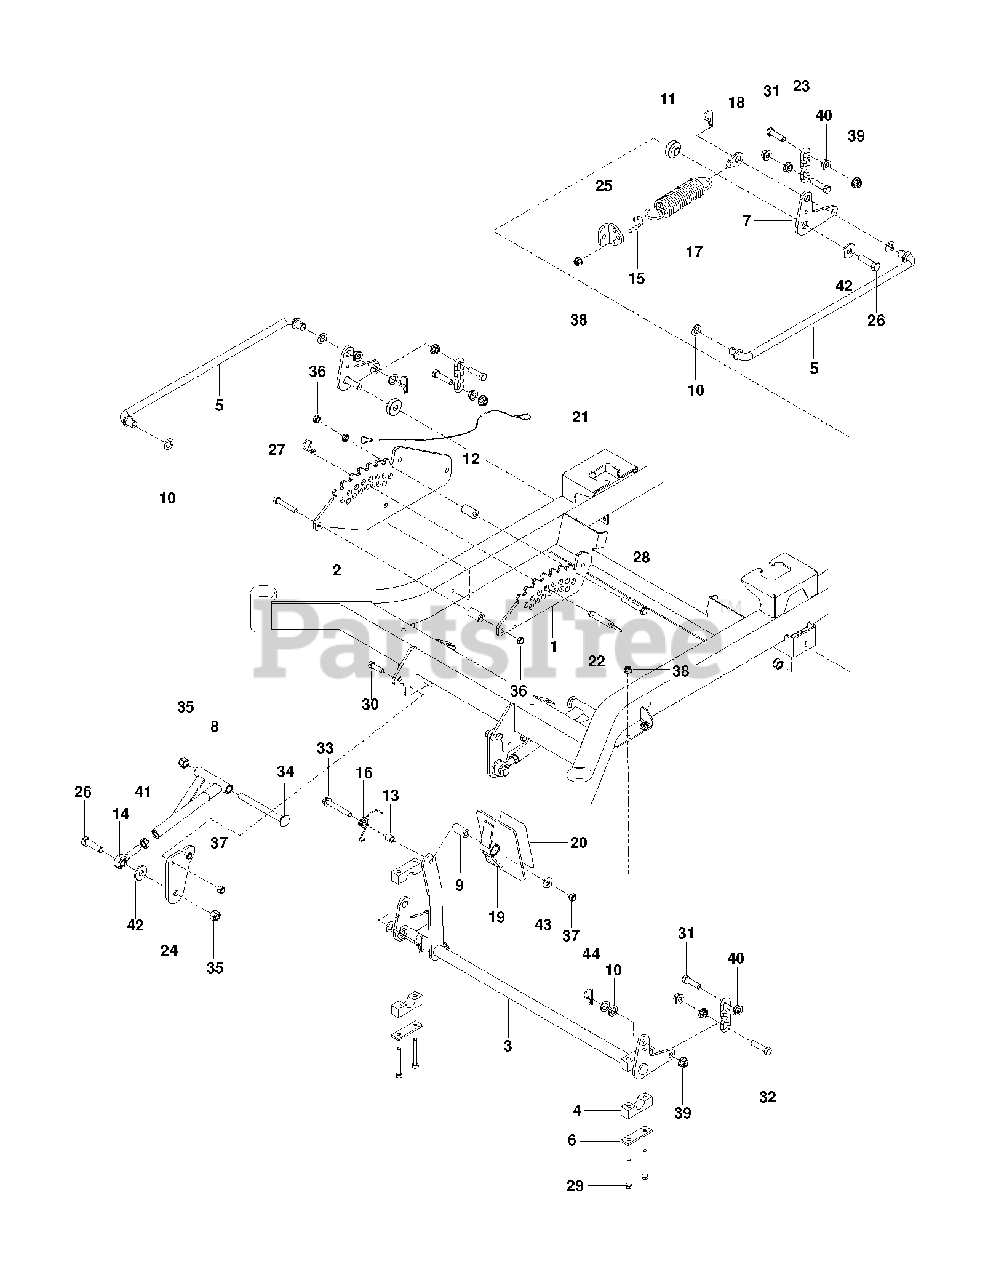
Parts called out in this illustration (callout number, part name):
1	PLATE, INSIDE 5", HEIGHT
2	PLATE, 5" HEIGHT
4	PILLOW BLOCK
5	CROSS LINK
6	REINFORCEMENT BAR
7	BELLCRANK, REAR LIFT
8	STRUT, DECK, BLK
9	BUSHING, SLEEVE
10	BUSHING
11	IDLER SPACER
12	DECK LIFT SPACER
14	ROD END
16	SPRING, TORSION
18	TAB, SPRING
19	PEDAL, FOOT, WELDMENT
20	FOOT PAD
21	LANYARD
22	HITCH PIN
23	LIFT CHAIN - 3 LINK
24	MOUNT, STRUT
25	MOUNT, SPRING
26	HCS 1/2-13 X 1 3/4 GR 8
27	HCS 3/8C X 2 1/4
28	HCS 3/8C X 2 1/2
29	HCS 5/16C X 2-3/4
30	HCS 3/8C X 1 1/4 GR5
31	HCS 7/16C X 1 1/2
32	HCS 7/16 - 14 X 1 3/4
33	HHFS 3/8-16 X 2 3/4
34	1/2-13X5-1/2 CAR BLT
35	NUT 1/2-13 HEX NYLOC ZD
36	NUT HEX 3/8-16 NYLON, THIN
37	NUT 3/8-16 NYLOC
38	5/16-18 NYLOC FLANGE NUT
39	NUT 7/16-14 HEX WHIZ LK
40	NUT 7/16C WHIZ
41	NUT 1/2-20 HEX JAM ZD
42	WASH USS FLAT 1/2
43	WASHER 3/8 FLAT
44	PIN, COTTER 1 3/4
